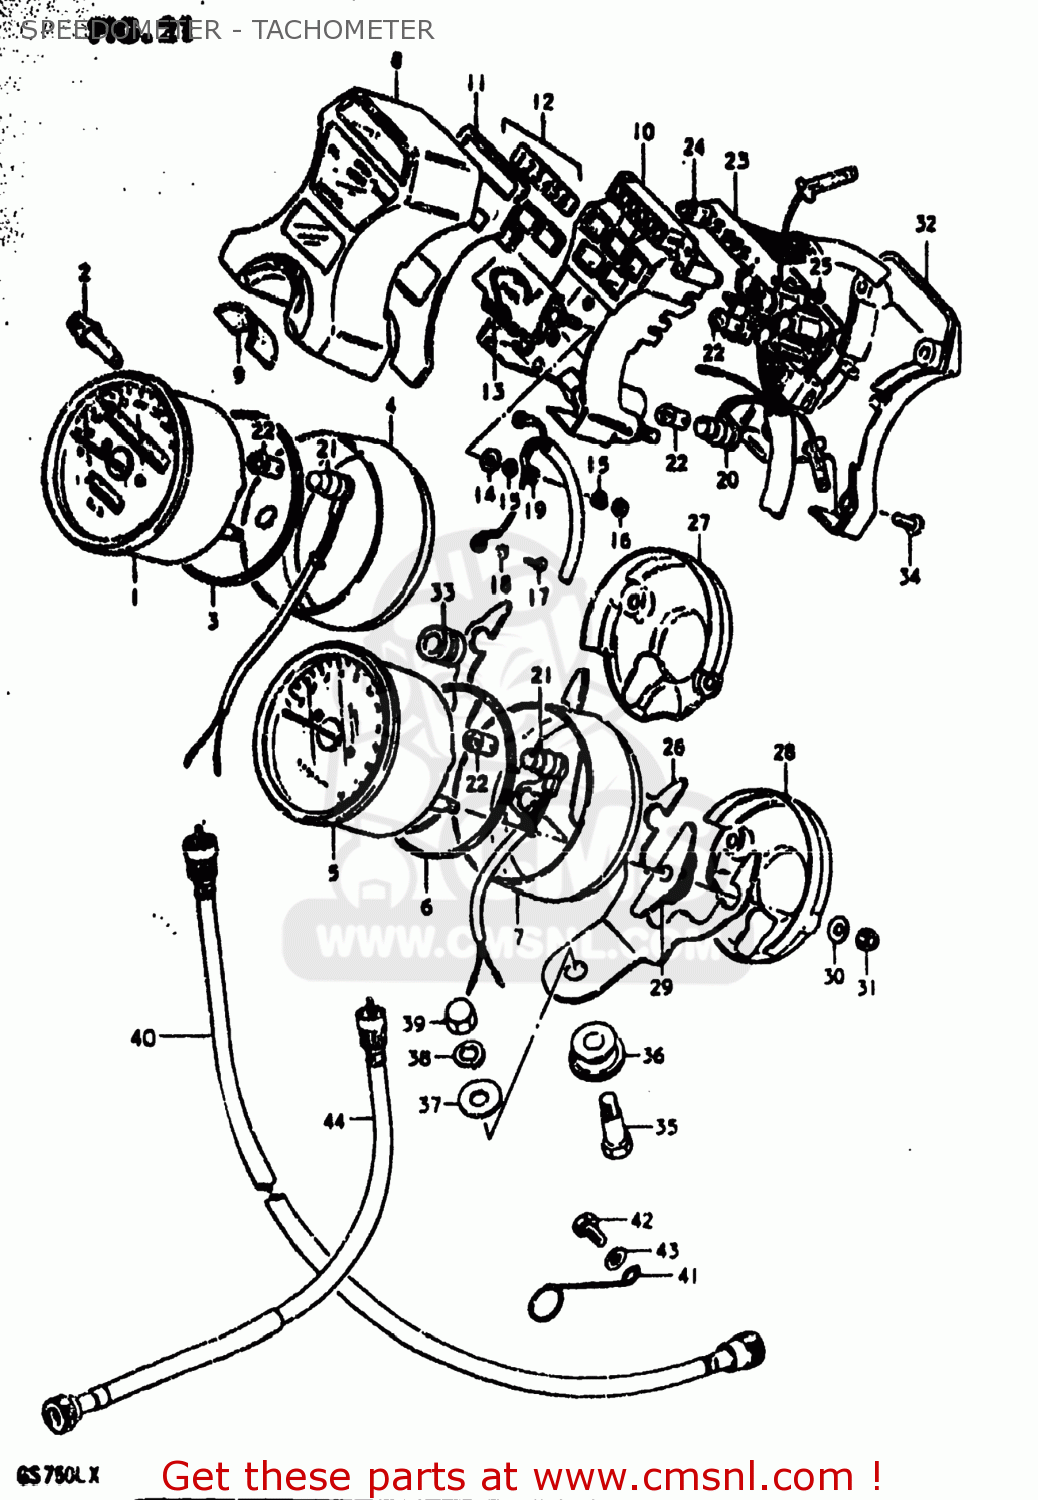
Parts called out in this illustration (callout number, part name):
1	METER,SPEEDOMETER
2	KNOB
3	CUSHION
4	COVER,SPEEDOMETER
5	TACHOMETER
6	CUSHION
7	COVER,TACHOMETER
8	CASE,PILOT BOX,OUTER
9	SEAL,IGNITION SWITCH
10	CASE, PILOT BOX INNER
11	PLATE,PILOT BOX
12	LENS SET,PILOT
13	METER,FUEL
14	WASHER
15	LOCK WASHER
16	NUT
17	SCREW
18	LOCK WASHER
19	LEAD WIRE, FUELMETER
20	SOCKET
21	SOCKET,METER
22	BULB(12V3.4W,T10)
23	SOCKET,GEAR INDICATOR
24	BULB(14V1.12W)
25	SCREW
26	BRACKET,COMBINATION METER
27	ORNAMENT,SPEEDOMETER
28	COVER,TACHOMETER
29	CUSHION,METER
30	WASHER
31	NUT
32	COVER,PILOT BOX,UNDER
33	CUSHION,PILOT BOX
34	SCREW,PILOT BOX
35	BOLT
36	CUSHION,METER
37	WASHER(8.5X23X1.2)
38	LOCK WASHER
39	NUT
40	CABLE ASSEMBLY,SPEEDOMETER
41	GUIDE,SPEEDOMETER CABLE
42	BOLT, UPPER
43	WASHER
44	CABLE ASSEMBLY,TACHOMETER
